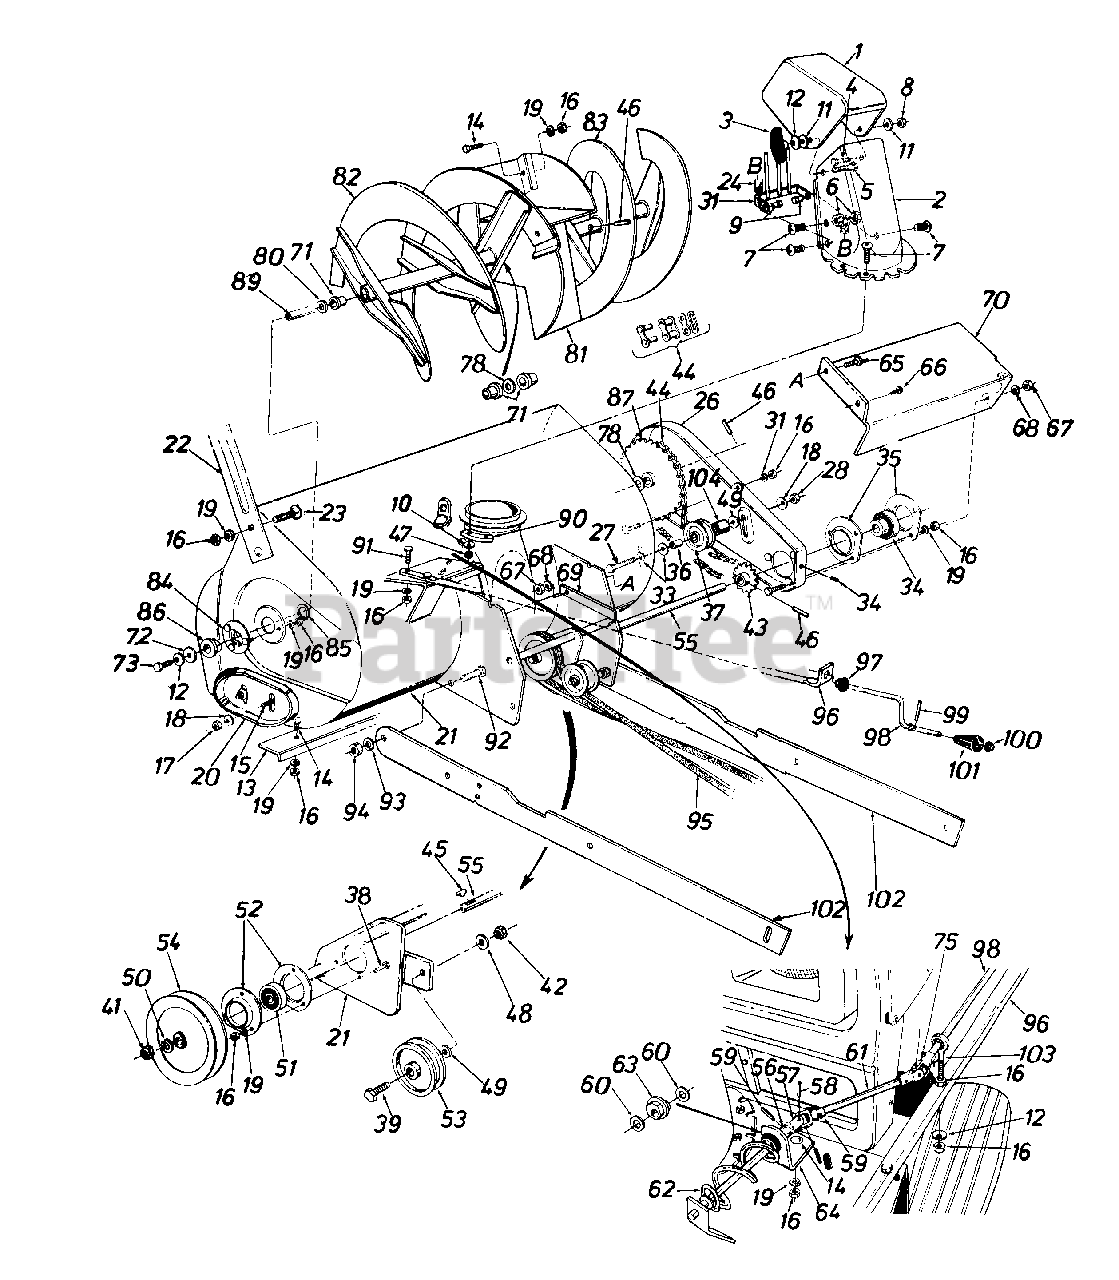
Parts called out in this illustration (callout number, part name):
1	Upper Chute
2	Lower Chute
3	Knob Handle Ass'y.
4	Truss Mach. Scr. 5/16-18 x .75" Lg.
5	Carriage Bolt 5/16-18 x 1" Lg.
6	Hex Cent. L-Nut 5/16-18 Thd.
7	Truss Mach. Scr. 1/4-20 x .75" Lg.
8	Hex Cent. L-Nut 5/16-18 Thd.
9	Shld. Nut 1/4-20 Thd.
10	Fl-Wash. 1/4" I.D.
11	Fl-Wash. .344" I.D. x 1.125"
12	Bell-Wash. .345" I.D. x .88"
13	Shave Plate
14	Carriage Bolt 5/16-18 x .62" Lg.
15	Carriage Bolt 3/8-16 x .62" Lg.
16	Hex Nut 5/16-18 Thd.
17	Hex Jam Nut 3/8-16 Thd.
18	Bell-Wash. .40" I.D. x .88"
19	L-Wash. 5/16" I.D.
20	Slide Shoe
21	Spiral Hsg. Ass'y. - 36"
22	Guide Blade
23	Carriage Bolt 5/16-18 x .62"
24	Extension Spring
26	Chain Guard Ass'y.
27	Hex Bolt 3/8-16 x 2" Lg.
28	Hex Ins. Nut 3/8-16 Thd.
31	Chute Guard Ass'y.
33	Fl-Wash. .385" I.D. x .87" O.D.
34	Ball Brg. .75" I.D.
35	Flangette
36	Spacer .375" I.D. x .60" O.D.
37	Flat Idler 1.875" Dia.
38	Hex Sems Bolt 5/18 x .75" Lg.
39	Hex Bolt 3/8-16 x 1.75" Lg.
41	Hex Jam Nut 3/4-10 Thd.
42	Hex Jam Nut 3/8-16 Thd.
43	Sprocket Ass'y. - 14 Teeth
44	#420 Chain x 1/2" Pitch - 77 Links
44	Master Link
45	061 Hi-Pro-Key 3/16 x 5/8"
46	Spring Pin Spir. 5/16" Dia. x 1.75" Lg.
47	Hex L-Nut 1/4-20 Thd.
48	L-Wash. 3/8" I.D.
49	Fl-Wash. .406" I.D. x 1.25"
50	Spr. L-Wash. 3/4" I.D.
51	Self-Aligning Brg.
52	Flangette
53	Idler Pulley
54	5/8 V-Pulley .75" I.D. x 6" O.D.
55	Drive Shaft Ass'y.
56	Joint Brkt. Ass'y.
57	Joint Block
58	Oval Head Rivet
59	Spiral Pin 1/8" Dia.
60	Fl-Wash. .385" I.D. x .62"
61	Chute Crank Ext. Rod
62	Chute Crank Ass'y. R.H.
63	Plastic Bushing .38" I.D.
64	Chute Crank Brkt.
65	Hex Bolt 1/4-20 x .62" Lg.
66	Hex Wash. S-Tap Scr. 1/4-20 x .50" Lg.
67	Hex Nut 1/4-20 Thd.
68	L-Wash. 1/4" I.D.
69	Belt Cover
70	Drive Shaft Cover
71	Plastic Bushing
72	Washer .39" I.D. x 1.75" O.D.
73	Hex Bolt 5/16-18 x .88" Spec.
75	Cotter Pin 3/32" Dia.
78	Fl-Wash. 1.03" I.D. x 1.62"
80	Fl-Wash. 1" I.D. x 1.75"
81	Rotor Paddle Ass'y.
85	Snap Ring for 1.5" Shaft
86	Flange Brg, w/flats 1" I.D.
87	Sprocket Hub Ass'y. 40 Teeth
89	Spiral Axle
90	Chute Flange Keeper
91	Hex Bolt 5/16-18 x 1.5" Lg.
92	Hex Bolt 1/2-13 x 1.25" Lg.
93	L-Wash. 1/2" I.D.
94	Hex Nut 1/2-13 Thd.
95	V-Belt
98	Chute Crank 34.5" Lg.
99	Roll Pin .12" Dia. x .63"
100	Push Nut 3/8" Rod
101	Knob Black
102	Linkage Arm
103	Eye Bolt 5/16-18 x 3" Lg.
104	Idler Spacer
